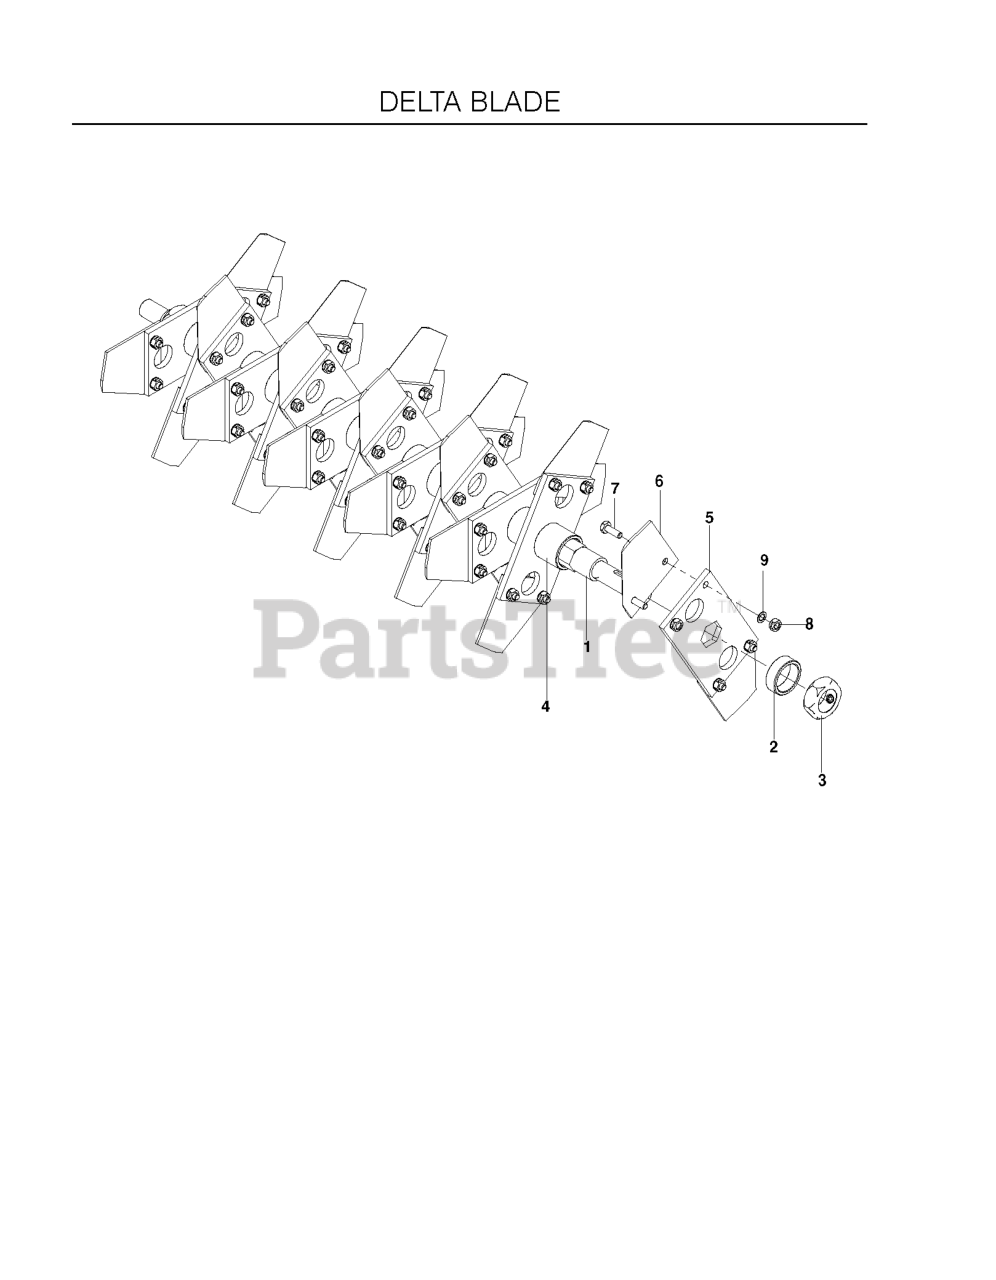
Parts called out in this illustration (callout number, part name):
2	END SPACER
3	JAM NUT W/SET SCREW
4	SPACER - LONG
5	BLADE MOUNTING PLATE
6	30 DELTA SET W/HARDWARE
7	HEX SCREW 1/4X.75
8	NUT 1/4C CENTER LOCK
9	TH CABLE AR# 441L-632-10
